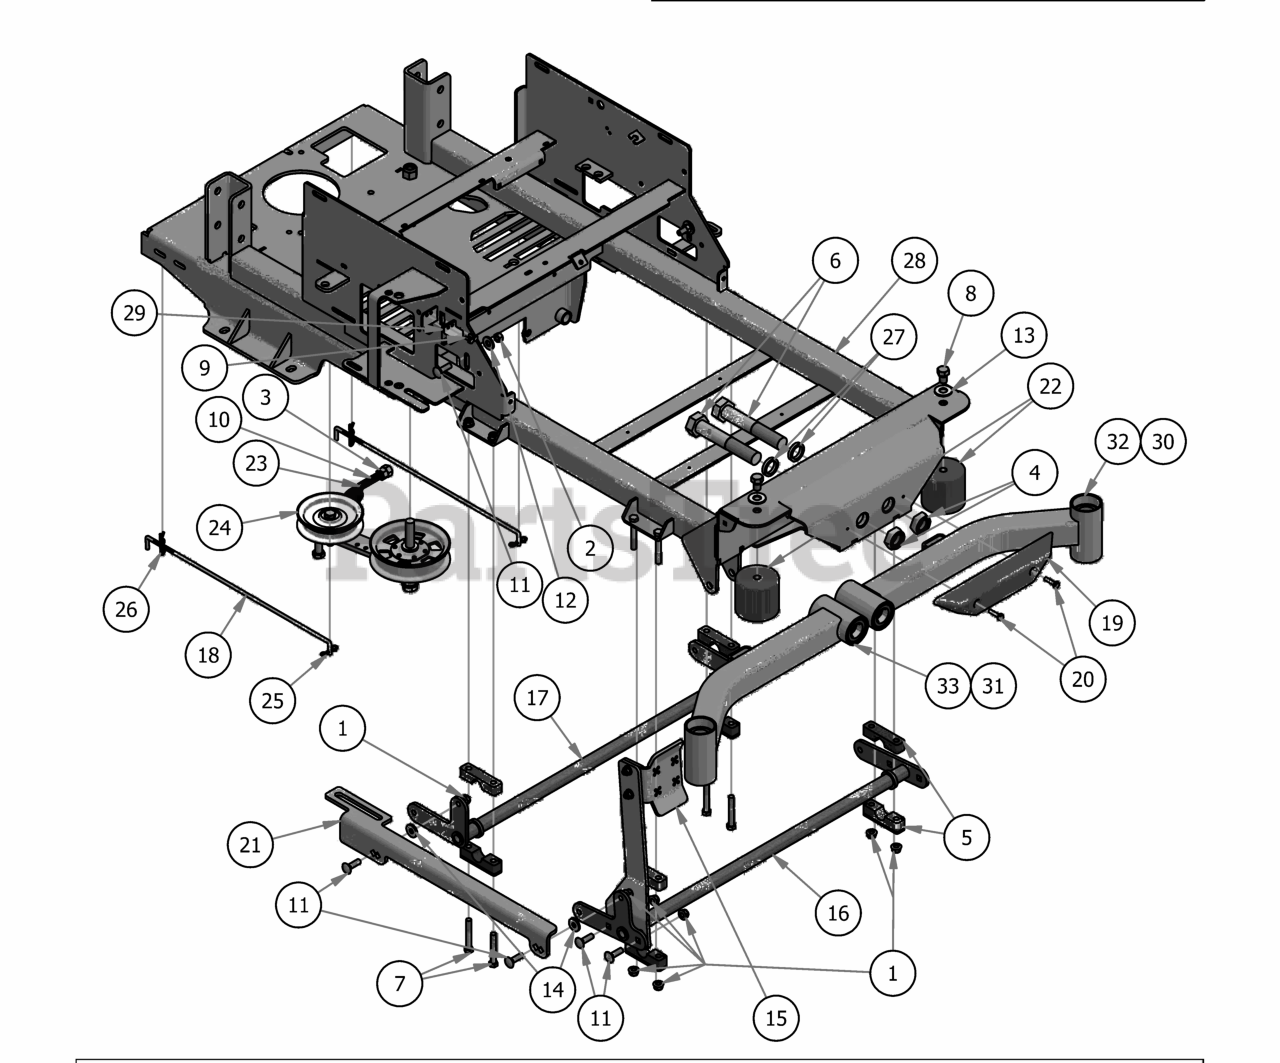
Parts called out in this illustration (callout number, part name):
1	3/8" Nylock Flange Nut
2	3/8" Hex Nut
3	1/2" Hex Nut
4	1" Fine Thread 1/2 Nylock Nut
5	Pillow Block Kit
6	1-14 x 5.5 Hex Bolt Grade 8 Zinc Yellow
7	3/8-16 x 2 1/2" Hex Bolt
8	1/2" x 3/4" Hex Bolt
9	12-24x 1/2 HWH Bolt
10	All Thread-Pump Idler Tensioner
11	3/8" x 1 1/4" Carriage Bolt
12	3/8" Flat Washer
13	1/2" Washer (Grade 8)
14	.360 ID Plastic Washer
15	Foot Pedal Assembly
16	Actuator Bar Front- 2017 MZ/ZT
17	Actuator Bar Rear- 2017 MZ/ZT
18	Neutral Rod
19	Front Bumper
20	1/4 x 1 Hex Head Tek screw
21	2017 MZ/ZT Actuator Linkage
22	Vibration Mount- Red Dot
23	Deck Idler Spring
24	EZT Pump Idler
26	Neutral Rod Clip
27	Spacer, 1x1.375x.25
28	2018 Maverick Frame
29	Safety Switch
30	2018 Maverick Suspension Arm Assembly-Left Short (48" Deck Only)
31	2018 Maverick Suspension Arm Assembly-Right Short (48" Deck Only)
32	2018 Maverick Suspension Arm Assembly-Long, Left
33	2018 Maverick Suspension Arm Assembly-Long, Right
